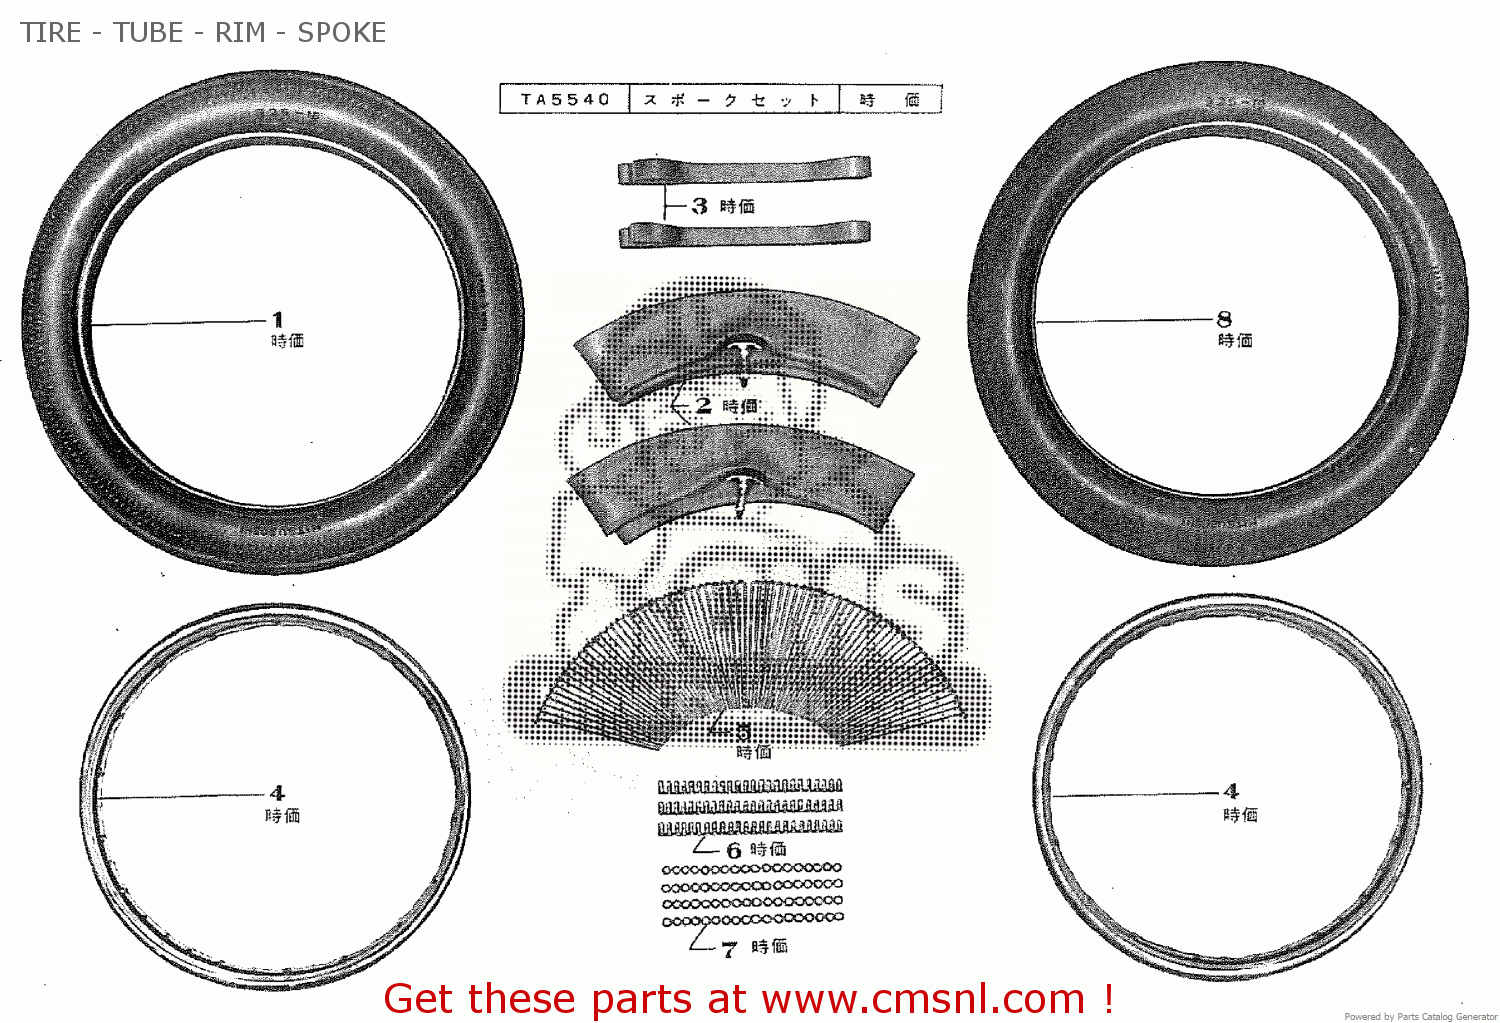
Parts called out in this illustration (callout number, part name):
1	FRONT TIRE
2	TUBE
3	FLAP
4	RIM
5	SPOKE
6	SPOKE NIPPLE
7	SPOKE WASHER
8	REAR TIRE
